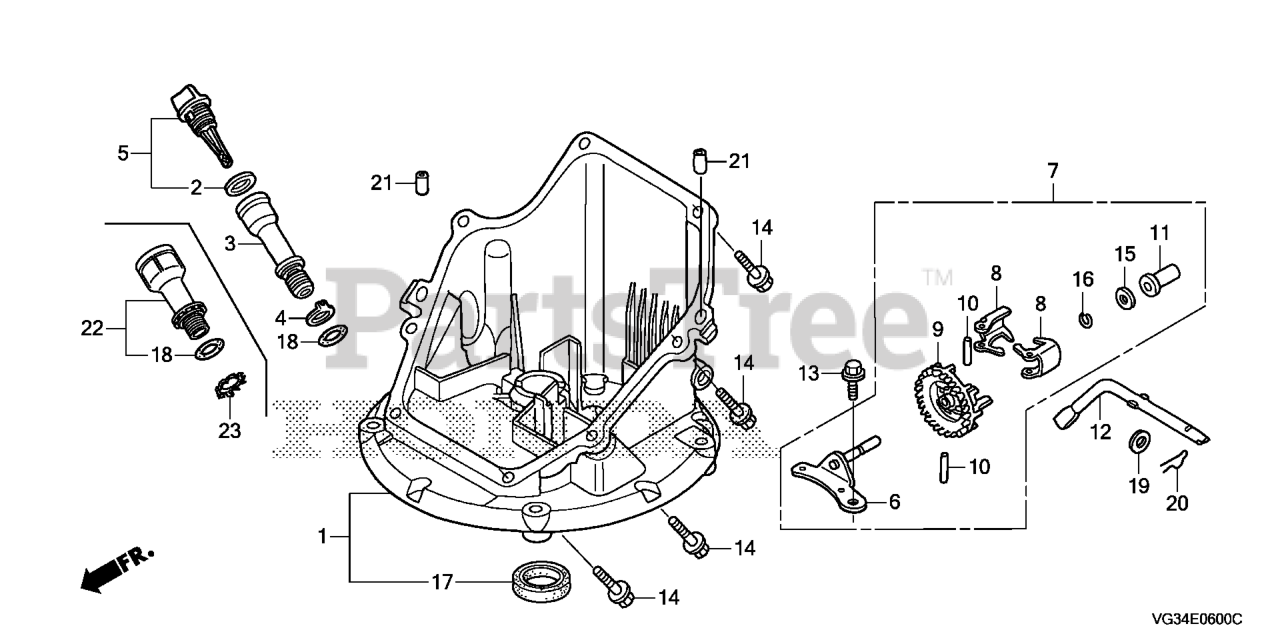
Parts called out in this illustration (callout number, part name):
1	PAN ASSY., OIL
2	GASKET, OIL FILLER CAP Use up to Engine SN 1257294.
5	DIPSTICK, OIL
6	SHAFT, GOVERNOR HOLDER
7	GOVERNOR ASSY.
8	WEIGHT, GOVERNOR
9	HOLDER, GOVERNOR WEIGHT
10	PIN, GOVERNOR WEIGHT
11	SLIDER, GOVERNOR
12	SHAFT, GOVERNOR ARM
13	BOLT, FLANGE (6X14)
14	BOLT, FLANGE (6X25) Use up to Engine SN 2056819.
15	WASHER, THRUST (6MM)
16	CLIP, GOVERNOR HOLDER
17	OIL SEAL (28X41.25X6)
18	O-RING (14.8X2.4) (ARAI)
19	WASHER, PLAIN (6MM)
20	PIN, LOCK (8MM)
21	PIN, DOWEL (8X20)
22	EXTENSION, OIL FILLER
23	WASHER, EXTENSION LOCK
